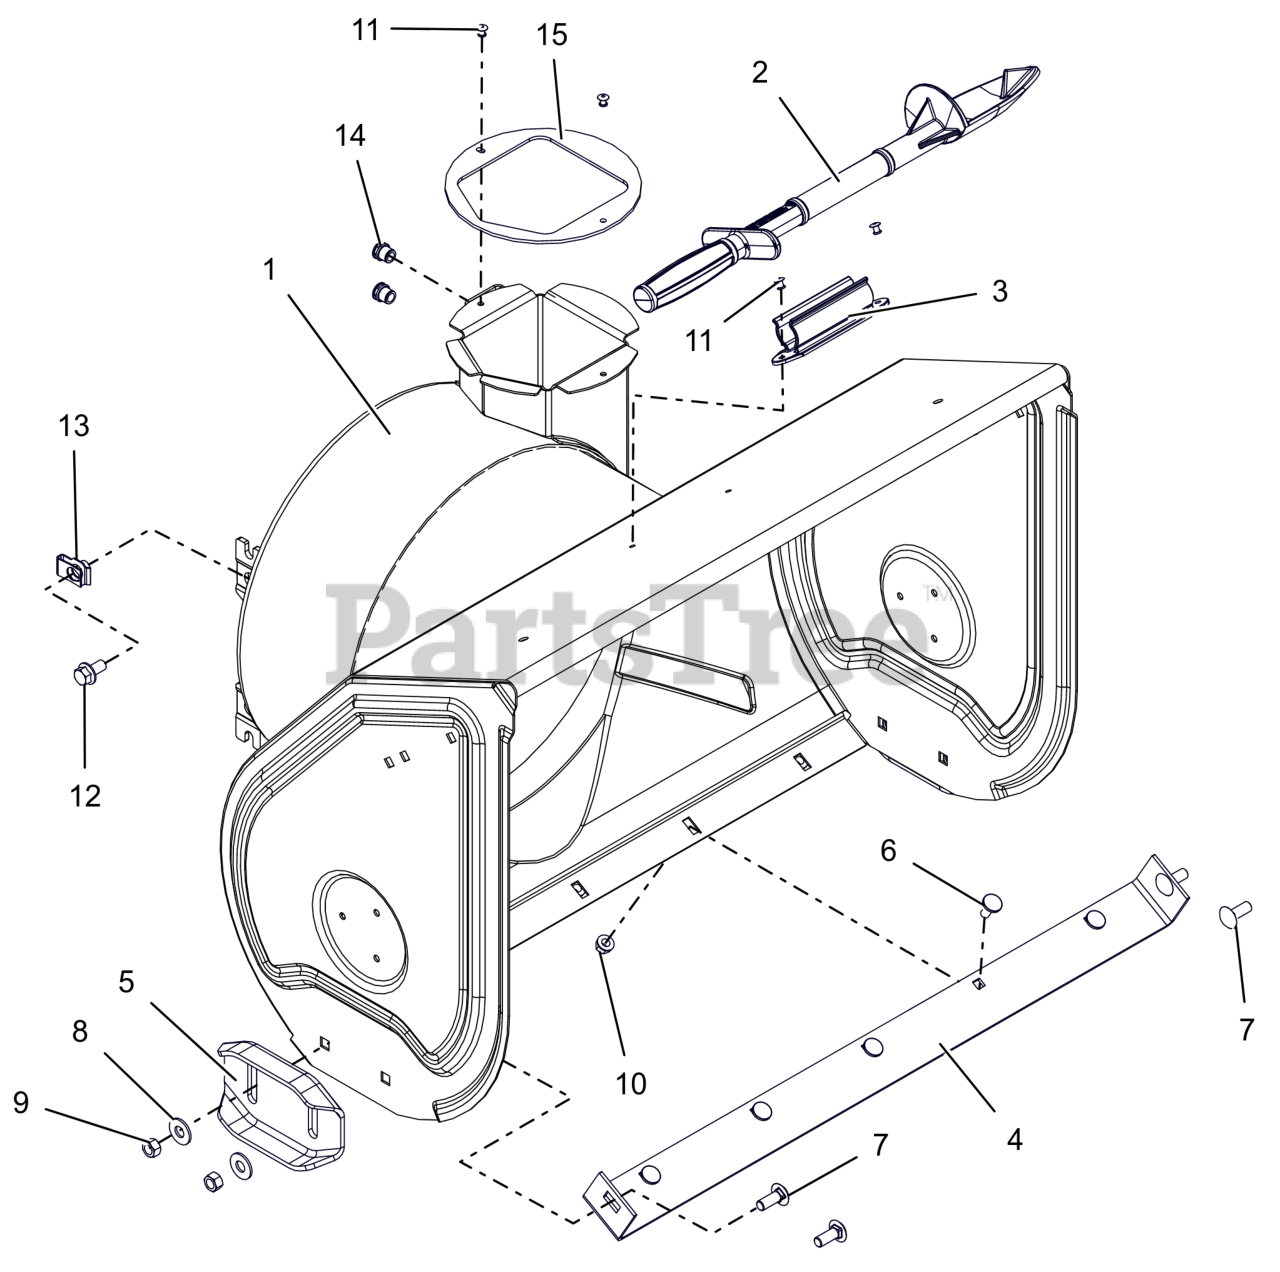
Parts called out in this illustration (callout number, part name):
1	BLOWER HOUSING W/DECAL 28"
2	DEVICE, SNOW CLEAN OUT
3	MOUNT, SNOW CLEAN OUT
4	BLADE, SCRAPER - 28"
5	SKID SHOE, REVERSIBLE - ORANGE
6	BOLT, MODIFIED HEAD CARRIAGE
7	BLT,RHSSN .38-16X1.00 G5 ZCC
8	WSHR,FLT .438X1.00X.083 ZCC
9	NUT-LK-CTR .38-16 ZC120
10	NUT-LK-TOP-FLG .312-18 GF ZCC
11	RVT, POP .1875 ZCC
13	NUT-RTNR .375-16X.37
14	NUT,THD,INSERT .38-16 ZC120
15	BAFFLE, DISCHARGE NECK
